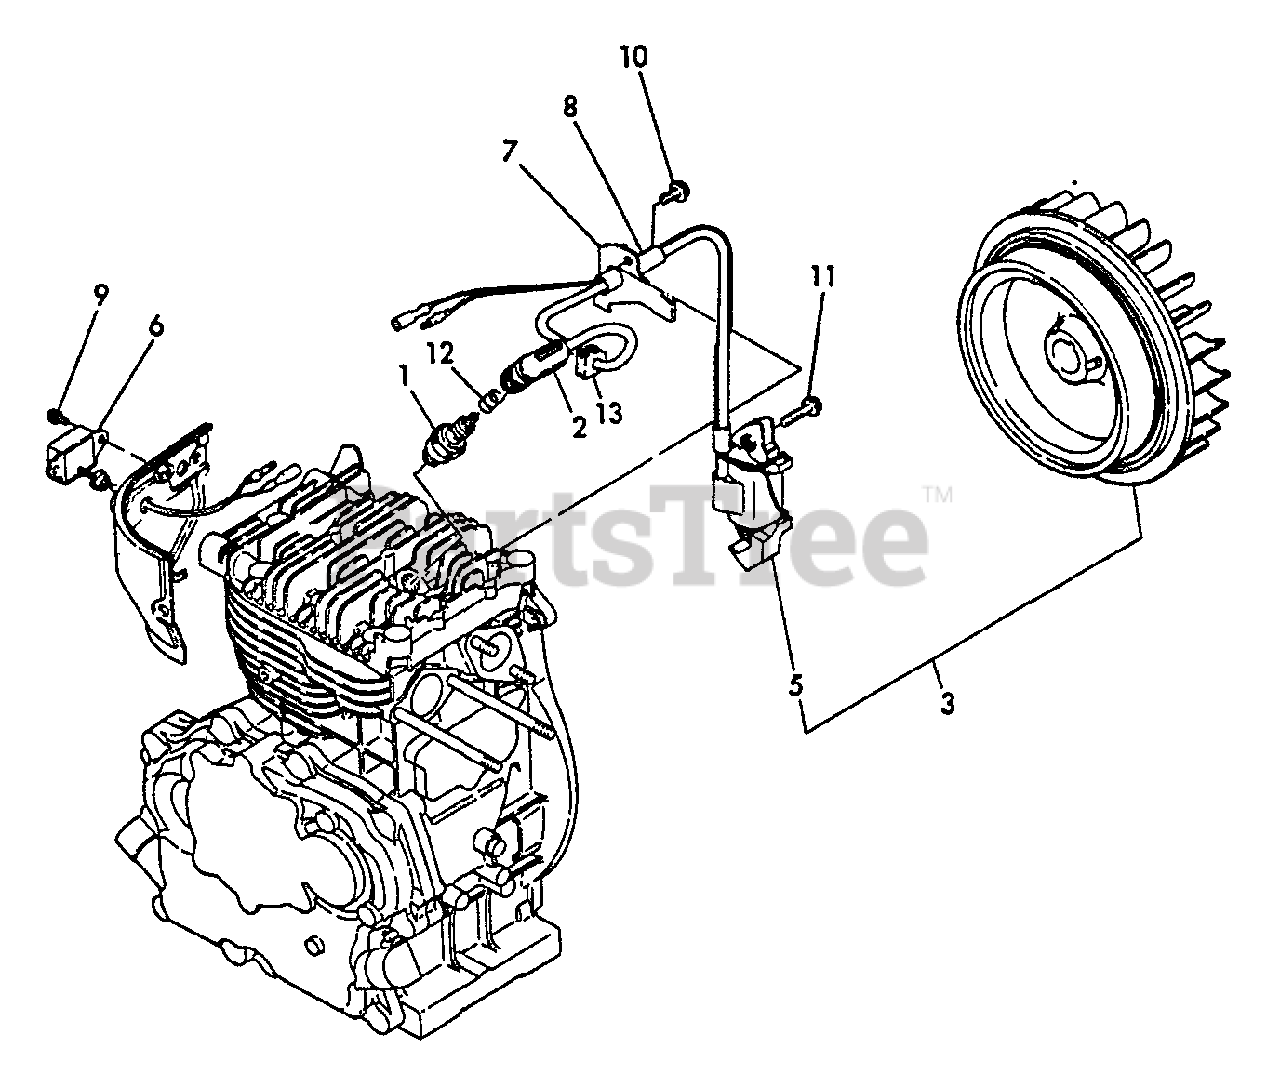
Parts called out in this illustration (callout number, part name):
1	SPARK PLUG
2	CAP, PLUG
3	FLYWHEEL W/MAGNET
5	COIL, IGNITION
6	IGNITER
7	CLAMP
8	TUBE, INSULATOR
9	SCREW - 5×10
10	BOLT - 6×8 -- PLATED
11	BOLT - 6×30
12	TERMINAL, SPARK PLUG CAP
13	GROMMET
